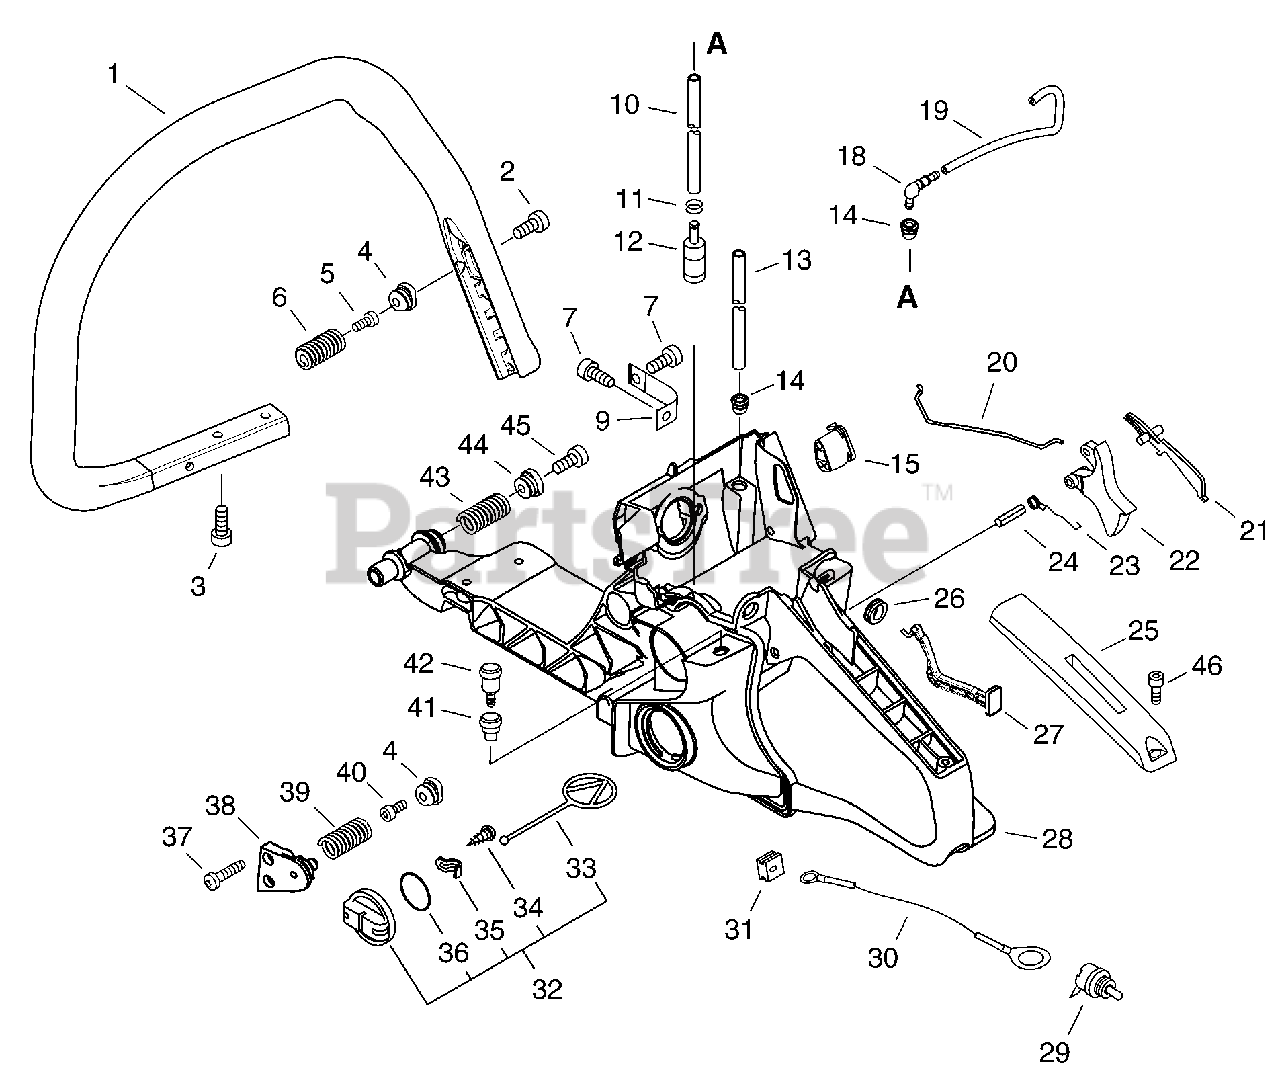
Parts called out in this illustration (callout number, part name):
1	HANDLE, FRONT
2	BOLT, TORX 6×20
3	BOLT, TORX 5×20
4	HOLDER, SPRING Ø14.4
5	BOLT, TORX 5×16
6	SPRING, COMPRESSION Ø17×38.4×2.6
7	BOLT, TORX 5×16
9	STRAP, SAFETY
10	PIPE, FUEL 3×5×120 BLACK
11	CLIP 6 MM
12	FILTER, FUEL
13	PIPE, IMPULSE 3×6(8)×160
14	GROMMET
15	GROMMET, NEEDLE
18	CONNECTOR, PIPE Ø5.4
19	PIPE, FUEL 3×6×135L
20	ROD, THROTTLE
21	LEVER, THROTTLE LOCKOUT
22	TRIGGER, THROTTLE
23	SPRING, TORSION
24	PIN, SPRING 4×25 SUS
25	COVER, HANDLE
26	GROMMET, CHOKE
27	ROD, CHOKE
28	HANDLE, REAR
29	SWITCH, ON-OFF
30	LEAD L= 170
31	GROMMET, LEAD
32	CAP ASSY, FUEL
33	CONNECTOR, CAP L= 60 MM
34	SCREW, TAPPING 3×8
35	RETAINER, CONNECTOR
36	O-RING 29
37	BOLT, TORX 5×20
38	HOLDER, SPRING
39	SPRING, COMPRESSION Ø17×36.7×2.6
40	BOLT, TORX 5×25
41	GROMMET, VENT
42	VENT ASSY
43	SPRING, COMPRESSION Ø20×40×3.3
44	HOLDER, SPRING Ø17
45	BOLT, TORX 6×20
46	BOLT, TORX 4×12
